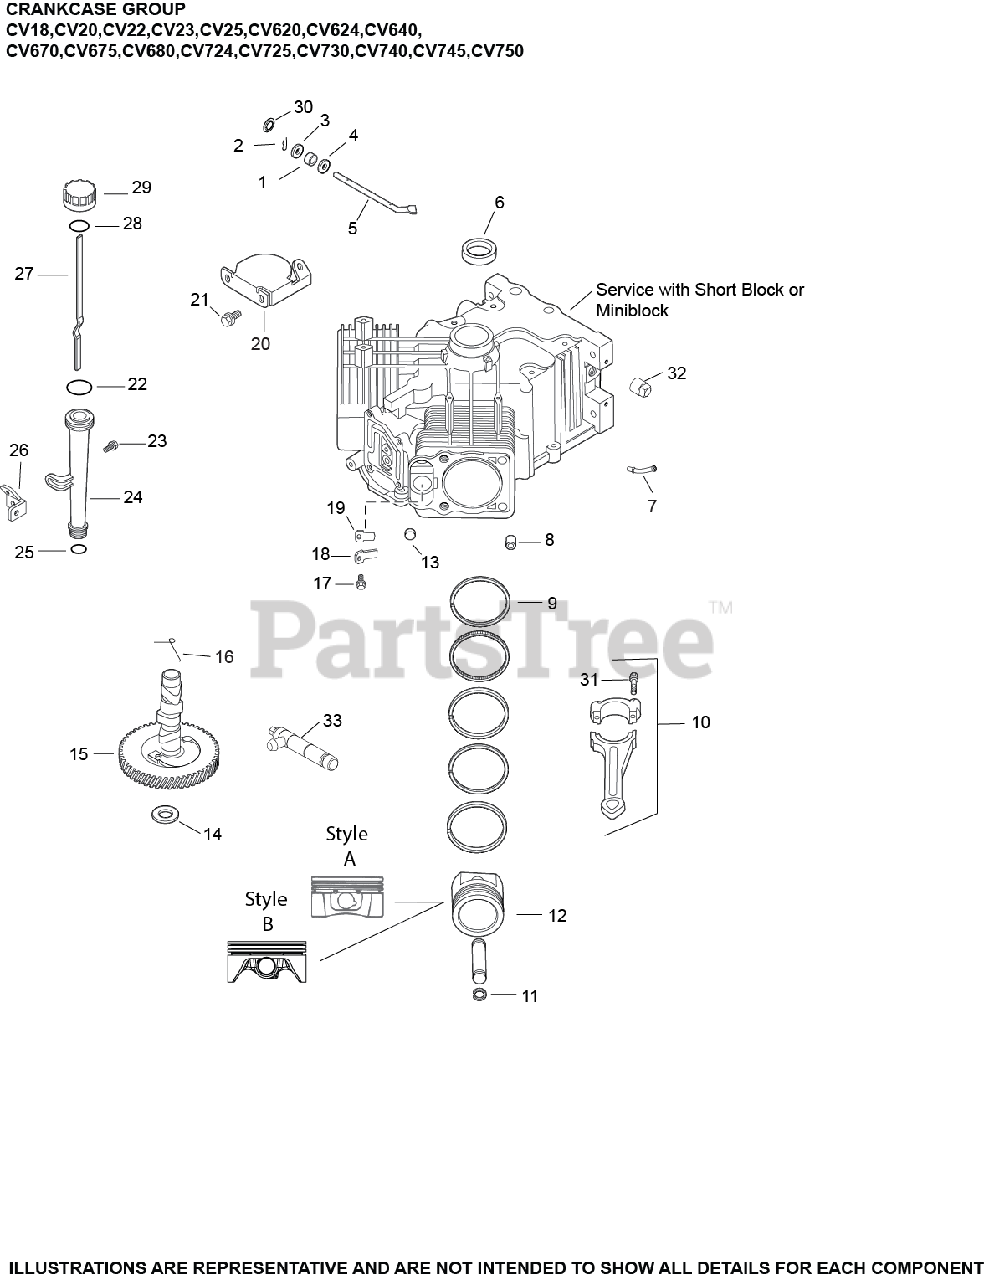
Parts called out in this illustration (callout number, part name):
1	SEAL, GOVERNOR CROSS SHAFT
3	WASHER, FLAT 9 MM
4	WASHER, FLAT 11/32"
5	SHAFT, GOVERNOR CROSS
6	SEAL, OIL (HELIX LIP)
8	PIN, LOCATING
9	RING SET (STYLE B) (STD)1.2MM TOP RING THICKNESS
9	RING SET (STYLE B) (.08)1.2MM TOP RING THICKNESS
9	RING SET (STYLE B) (.25)1.2MM TOP RING THICKNESS
9	RING SET (STYLE B) (.50)1.2MM TOP RING THICKNESS
10	KIT, CONNECTING ROD ASSEMBLY USE 25 067 04-S
10	KIT, CONNECTING ROD ASSEMBLY (.25 mm)
11	RETAINER, PISTON PIN
12	PISTON W/RINGS (STYLE B)(STD) - RING SET 24 108 26-S
12	PISTON W/RINGS (STYLE B)(.08) - RING SET 24 108 27-S
12	PISTON W/RINGS (STYLE B)(.25) - RING SET 24 108 28-S
12	PISTON W/RINGS (STYLE B)(.50) - RING SET 24 108 29-S
13	PLUG, CUP
15	KIT, CAMSHAFT
17	SCREW, FLG THD FRM M5X.8X10
17	SCREW, FLG THD FRM M5X0.8X13
18	RETAINER, BREATHER REED
19	REED, BREATHER
22	O-RING, UPPER OIL FILL TUBE
24	TUBE ASSEMBLY
25	O-RING, LOWER OIL FILL TUBE
26	BRACKET, OIL FILL TUBE
27	DIPSTICK, ASSY
28	O-RING, DIPSTICK
29	KIT, OIL FILL CAP (BLACK)
30	RETAINER, RING
